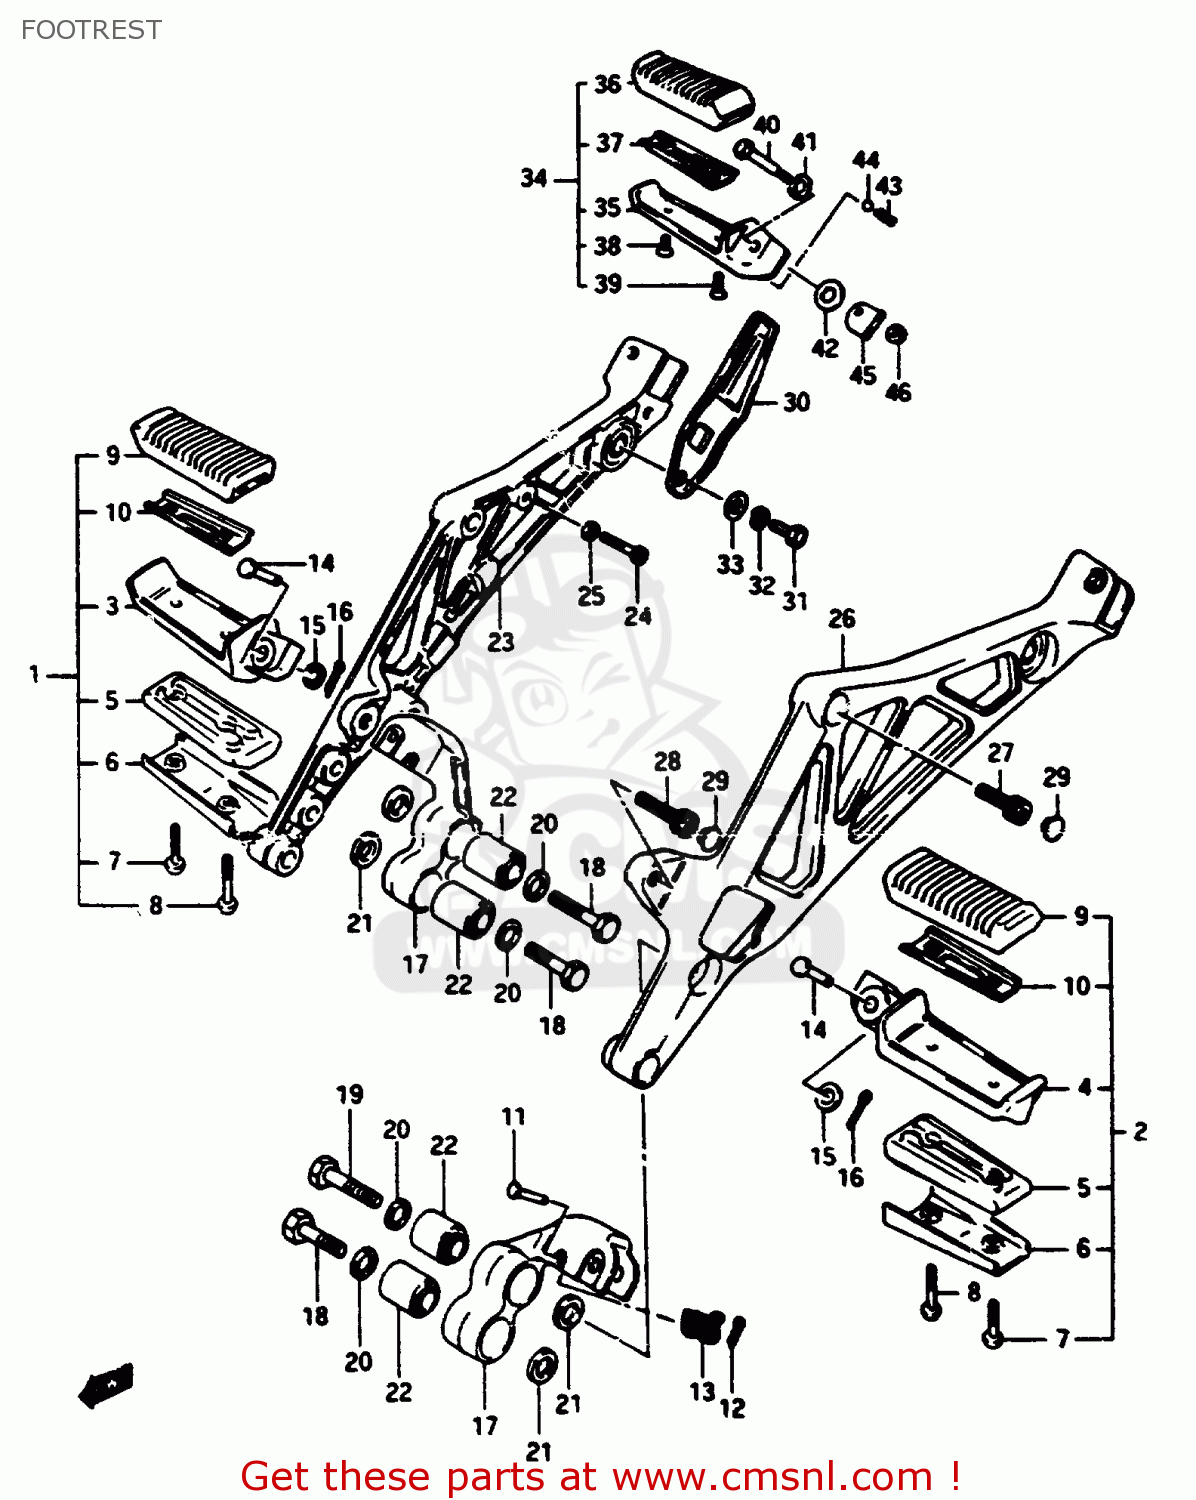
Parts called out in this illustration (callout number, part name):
1	FOOTREST ASSY,FR,R
2	FOOTREST ASSEMBLY,FRONT,LEFT
3	BAR,FRONT FOOTREST,RIGHT
4	BAR,FR FOOTREST,L
5	BAR,FR FOOTREST NO.2
6	COVER,FRONT FOOTREST B
7	SCREW
8	SCREW
9	RUBBER,FOOTREST
10	PLATE,FR FOOTREST RUBBER
11	PIN
12	PIN 20X20
13	SPRING
14	PIN
15	WASHER
16	PIN 20X20
17	HOLDER,FRONT FOOTREST
18	BOLT 10X40
19	BOLT
20	WASHER
21	WASHER(10.5X20X3.2)
22	BUSHING
23	BRACKET,MUFFLER,RIGHT
24	BOLT
25	NUT 6MM
26	BRACKET,MUFFLER,LEFT
27	BOLT
28	BOLT, CENTER
29	CAP
30	GUIDE,REAR FOOT
31	BOLT 8X12
32	LOCK WASHER
33	WASHER
34	FOOTREST ASSY,PILLION,R
35	BAR,PILLION FOOTREST,LEFT
36	RUBBER,RR FOOTREST
37	PLATE,RUBBER STOPPER
38	SCREW 5X12
39	SCREW 5X16
40	BOLT
41	WASHER
42	SHIM(8.2X22X0.2)
43	SPRING
44	BALL
45	PLATE,SPRING STOP,R
46	NUT
